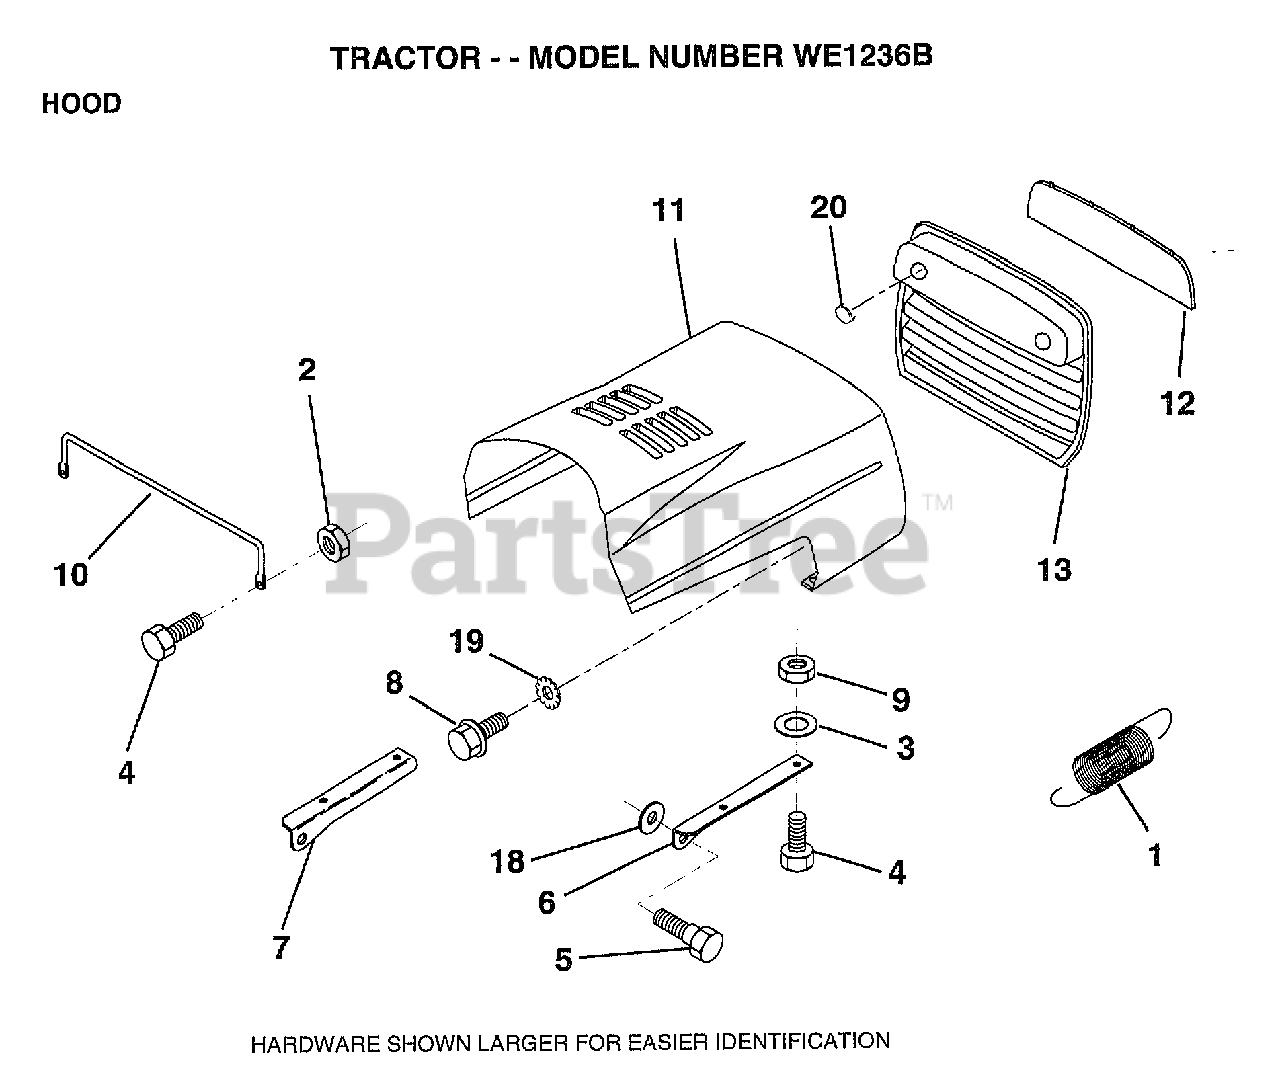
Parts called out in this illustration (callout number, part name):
1	EXT SPRING
2	NUT
3	WASHER
5	BOLT.SHLD.5/16-18
6	BRKT HOOD RH
7	BRKT HOOD LH
8	SCREW SLTD HXHD
9	NUT
10	"BRACE,HOOD"
11	HOOD.IMPREG.MS550
12	LENS
13	GRILL
18	WASHER
19	LOCKWASHER GT
